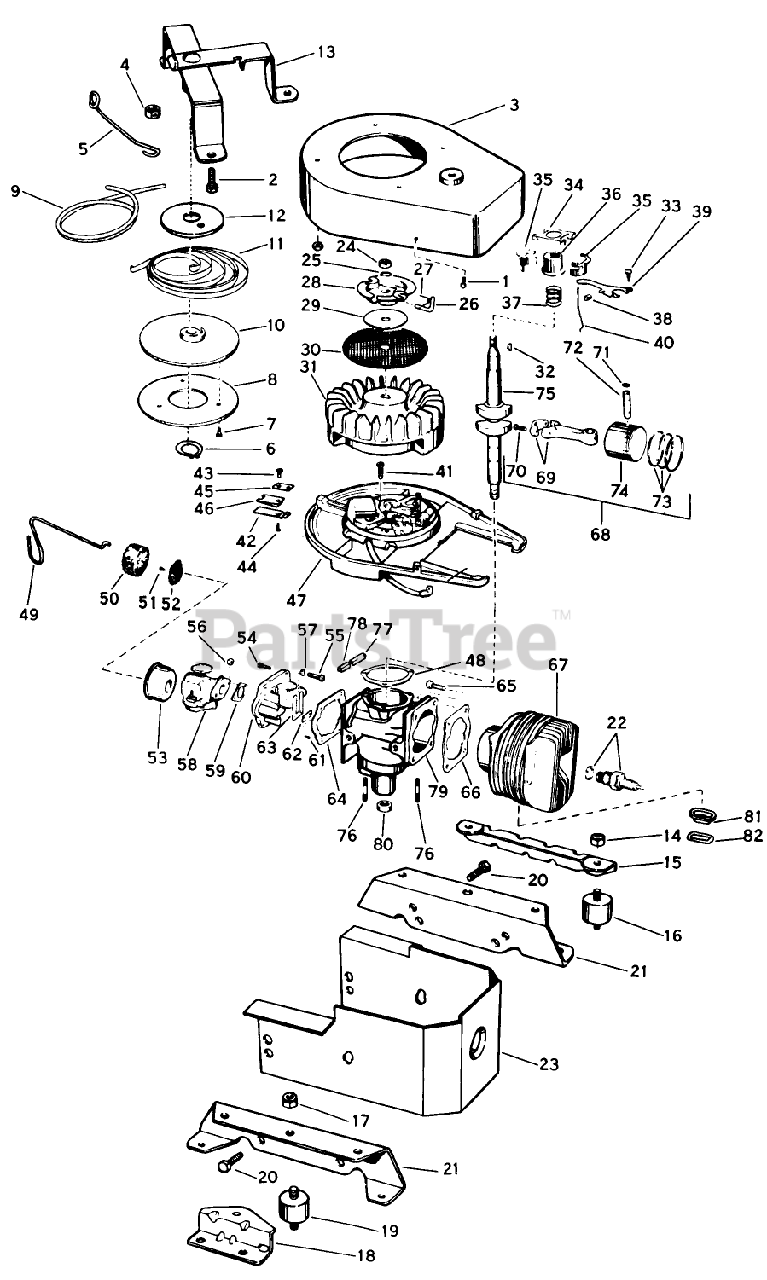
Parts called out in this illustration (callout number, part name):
1	SCREW S
6	Ring-Grip (Starter Brg. Pin)
9	Rope-Starter
11	RECOIL SPRING
12	Washer-Starter Spring Ret.
15	Bracket-Shock Mounting, Housing, Left
16	Mount-Rubber, Left
18	Bracket-Shock Mounting, Housing, Right
19	Mount-Rubber, Right
20	Screw-Stabilizer Bracket
21	Bracket-Shock Mtg., Engine
22	Spark Plug
23	Shield-Cylinder and Crankcase
26	PIN - STARTER
36	COLLAR S
37	Spring-Governor
38	WEAR BLOCK S
39	GOVERNER LEVER AY
40	GOVERNOR ROD S
44	Screw Shut-off Switch
46	Cover-Shut-off Switch Contact
48	GASKET S
49	Clip-Air Filter
50	ELEMENT
53	Cup-Air Filter
54	SCREW S
56	STOP NUT
59	GASKET S
62	PLATE-BACKUP, REED
68	Piston and Con. Rod Assembly
70	Screw-Connecting Rod
75	Crankshaft
76	Stud-Crankcase to Muffler
77	Shield-Dust, Crankcase, Right
78	Shield-Dust, Crankcase, Left
